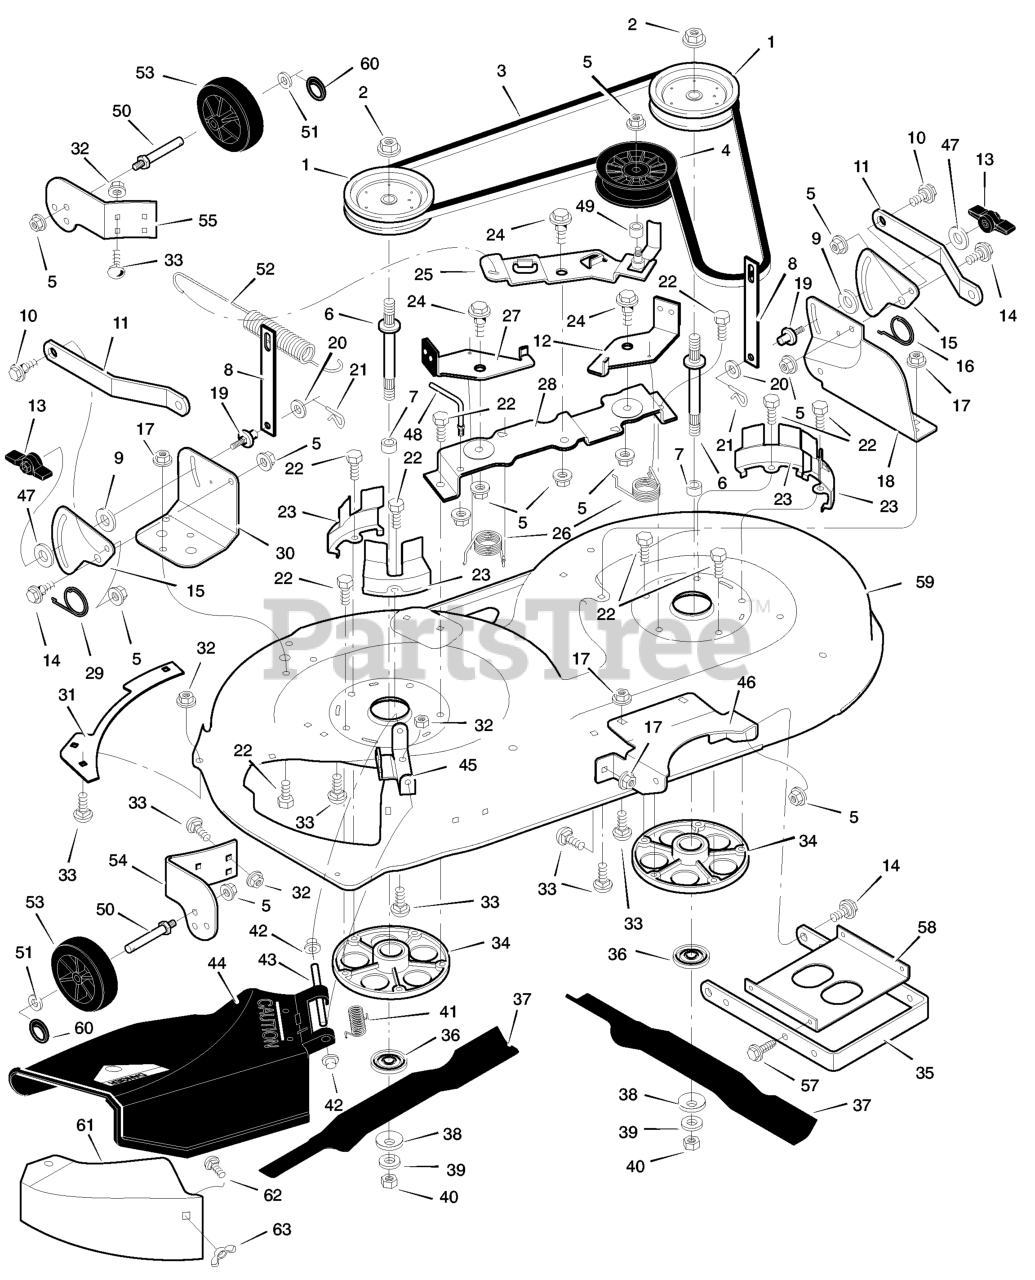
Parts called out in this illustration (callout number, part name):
1	Pulley, Jackshaft
2	Nut, Hex
3	Belt, Mower Drive
4	Pulley, Idler
5	Nut, Flange
6	Jackshaft
7	Spacer
8	Link, Lift
9	Pad, Friction
10	Bolt, Shoulder
11	Bracket, Suspension
12	Pad Assembly, Left Brake
14	Bolt, Shoulder
15	Plate, Suspension
17	Nut, Flange
18	Bracket, Suspension
19	Pin, Hanger
21	Pin, Hair
22	Bolt
23	Cover, Pulley
24	Bolt, Shoulder
25	Arm, Idler
27	Pad Assembly, Right Brake
28	Bracket, Brake
30	Bracket, Suspension
32	Nut, Flange
33	Bolt, Carriage
34	Mandrell Housing
35	Bracket, Suspension
36	Adapter, Blade
42	Cap, Push On
43	Rod, Deflector
44	Deflector Assembly
45	Bracket, Deflector Hinge
46	Bracket, Front Hanger
48	Guide, Belt
50	Bolt, Axle
52	Spring, Extension
53	Wheel, Gage
54	Bracket, Right Wheel
55	Bracket, Left Wheel
58	Stiffener
59	Housing, Blade
60	Ring, Locking
61	Plate, Mulcher
62	Bolt, Carriage
63	Wingnut
